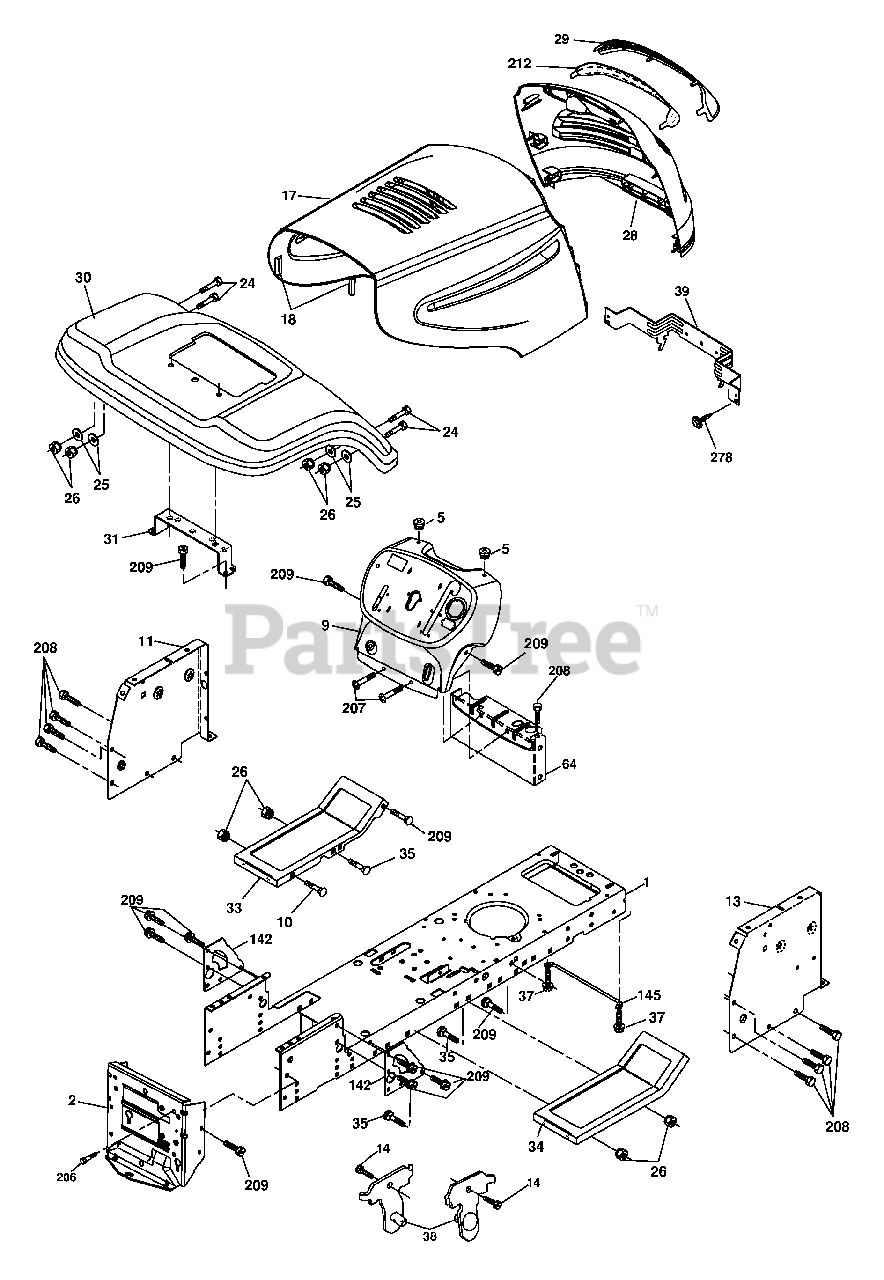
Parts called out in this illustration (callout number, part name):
1	Chassis
2	Drawbar
5	Bumper Hood/Dash
9	Dash
10	Bolt Carriage 3/8-16 x 1
11	Panel Dash Lh
14	Screw Thdrol 3/8-16x 1-1/4
17	Hood
18	Bumper Hood
24	Bolt Fin Hex 3/8-16 x 1 Gr. 5
25	Washer 13/32 x 13/16 x 12 Ga.
26	Nut Lock Hex W/Ins 3/8-16 unc
28	Grille
29	Lens
30	Fender Footrest STLT Pnt
31	Bracket Support Fender
33	Footrest Pnt Lh
34	Footrest Pnt Rh
35	Bolt Rdhd Sht Sqnk 3/8-16 x 3/4
37	Screw Thdrol 6/16-18 x 1/2 TYT
38	Bracket Asm. Pivot Mower Rear
39	Bracket Pivot
64	Dash Lower STLT
142	Plate Reinforcement STLT
145	Rod Pivot Chassis/Hood
206	Bolt Shoulder 5/16-18
207	Screw Thdrol 5/16-18 x 1/2
208	Screw Thdrol 3/8-16 x 1/2
209	Screw Hex Wsh Thdr.3/8-16 x 3/4
212	Insert Lens Reflect
278	Screw 10 x 3/4 Single Lead-Hex
